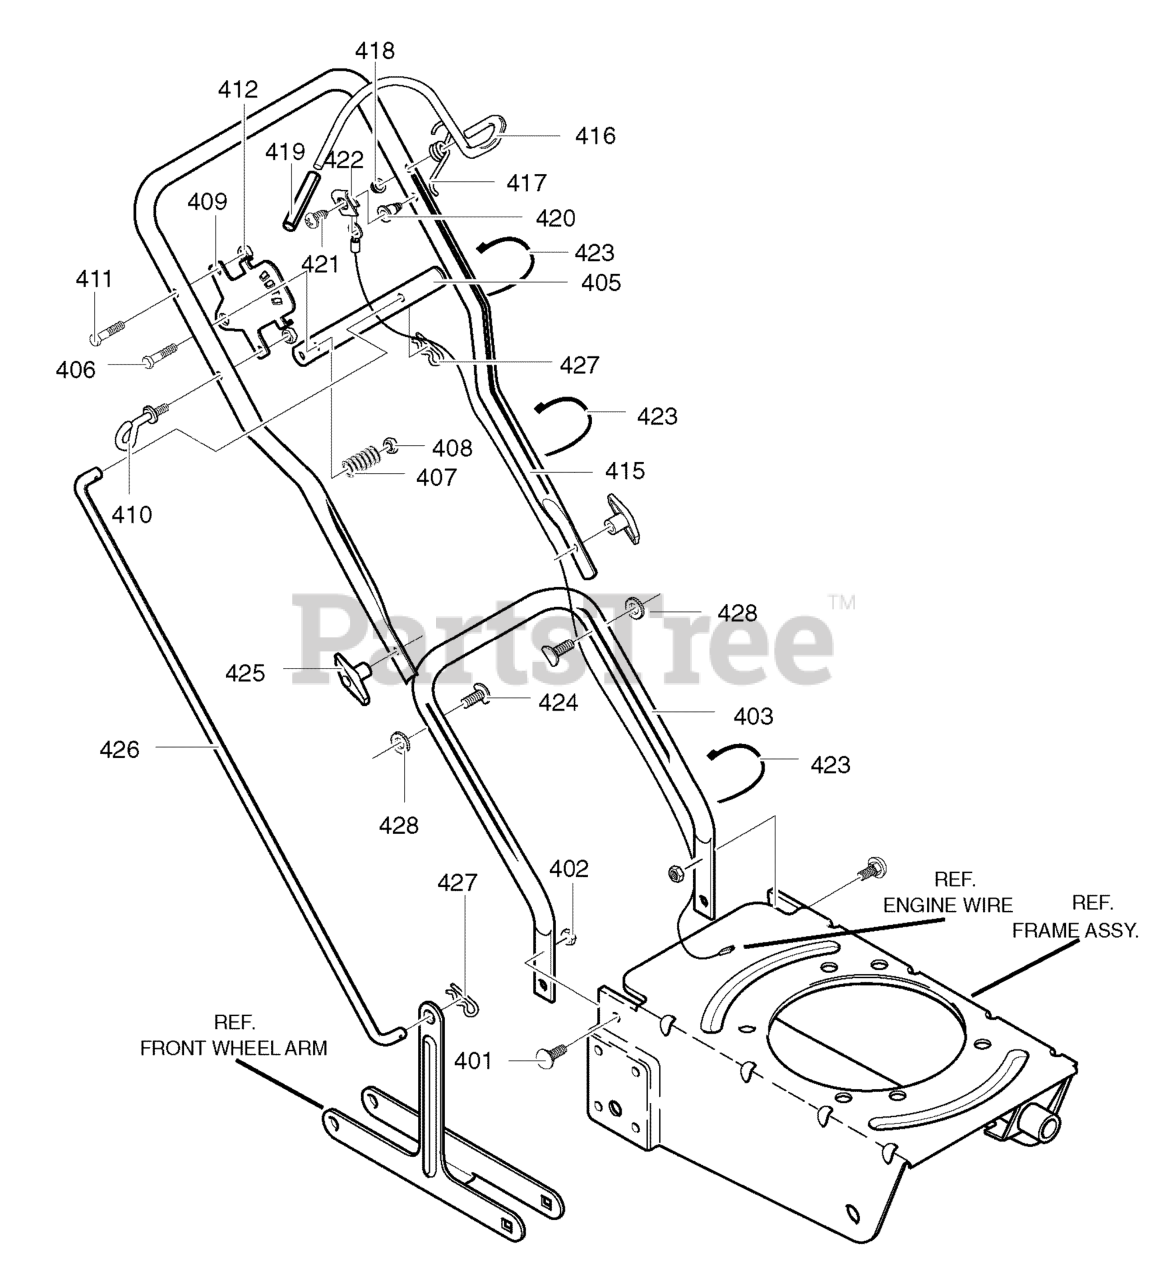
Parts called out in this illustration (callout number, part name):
401	BOLT, 5/16-18x.75
402	NUT, 5/16-18
403	HANDLE, Lower
405	HANDLE, Depth
407	SPRING, Compression
408	NUT, 5/16-18
409	BRACKET, Adjustment Quadrant
410	GUIDE, Rope
411	SCREW, 1/4-20x1.25
412	NUT, 1/4-20
415	HANDLE, Upper
416	BAIL, Operator Control
417	SPRING, Torsion
418	NUT, Push On
419	CAP, Operator Control
420	INSULATOR, Operator Control
421	SCREW, #6x.50
422	CLIP, Grounding
423	CABLE TIE
424	BOLT, 5/16-18x.75
425	WING KNOB 5/16-18
426	ROD, Control
427	PIN, HAIR
